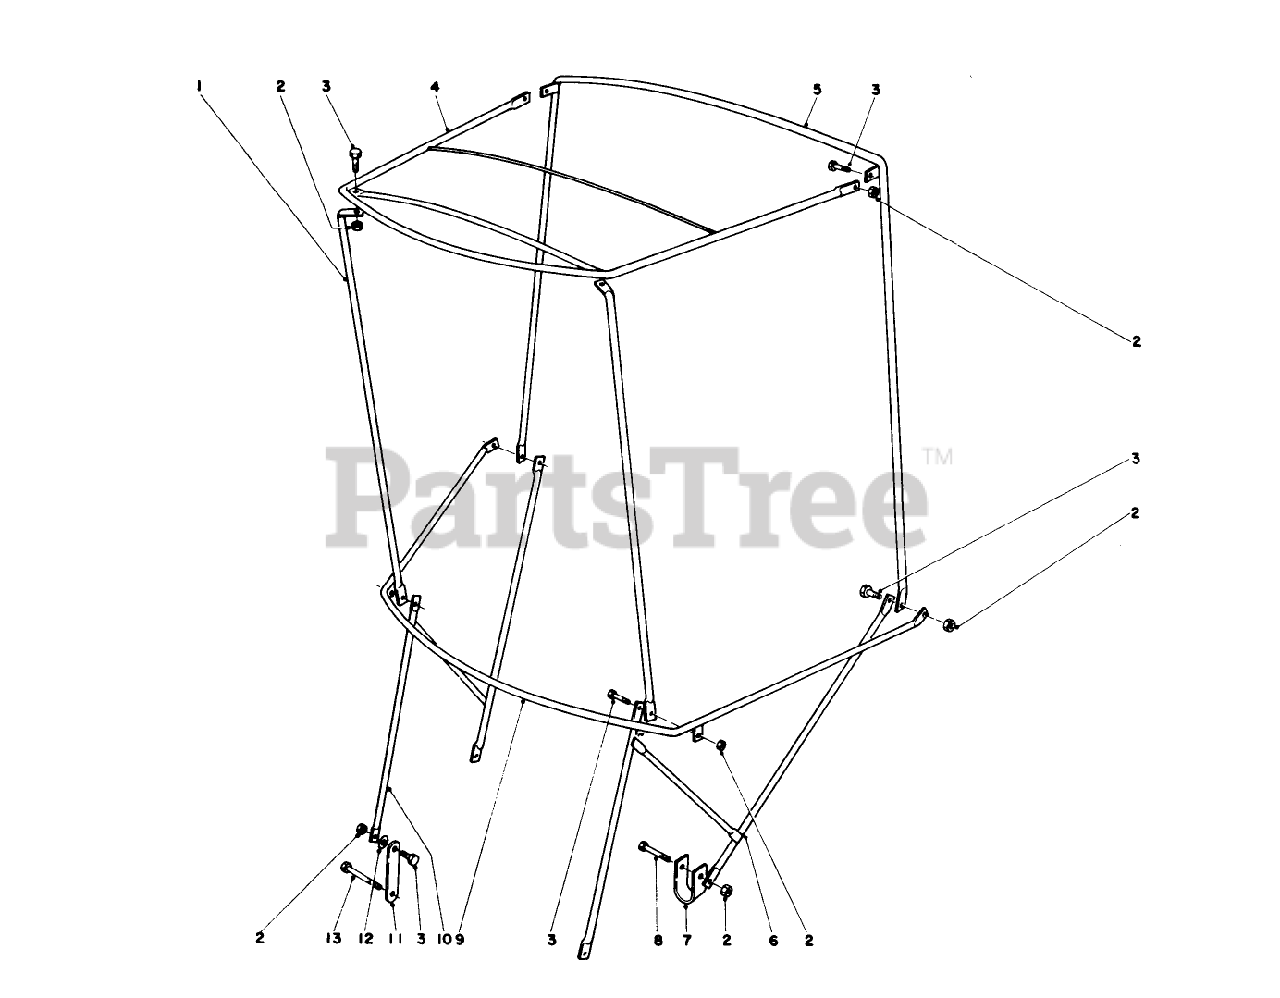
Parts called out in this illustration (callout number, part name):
3	SCREW-HH
8	SCREW-HH
12	WASHER-LOCK/EXT
13	SCREW-HH
